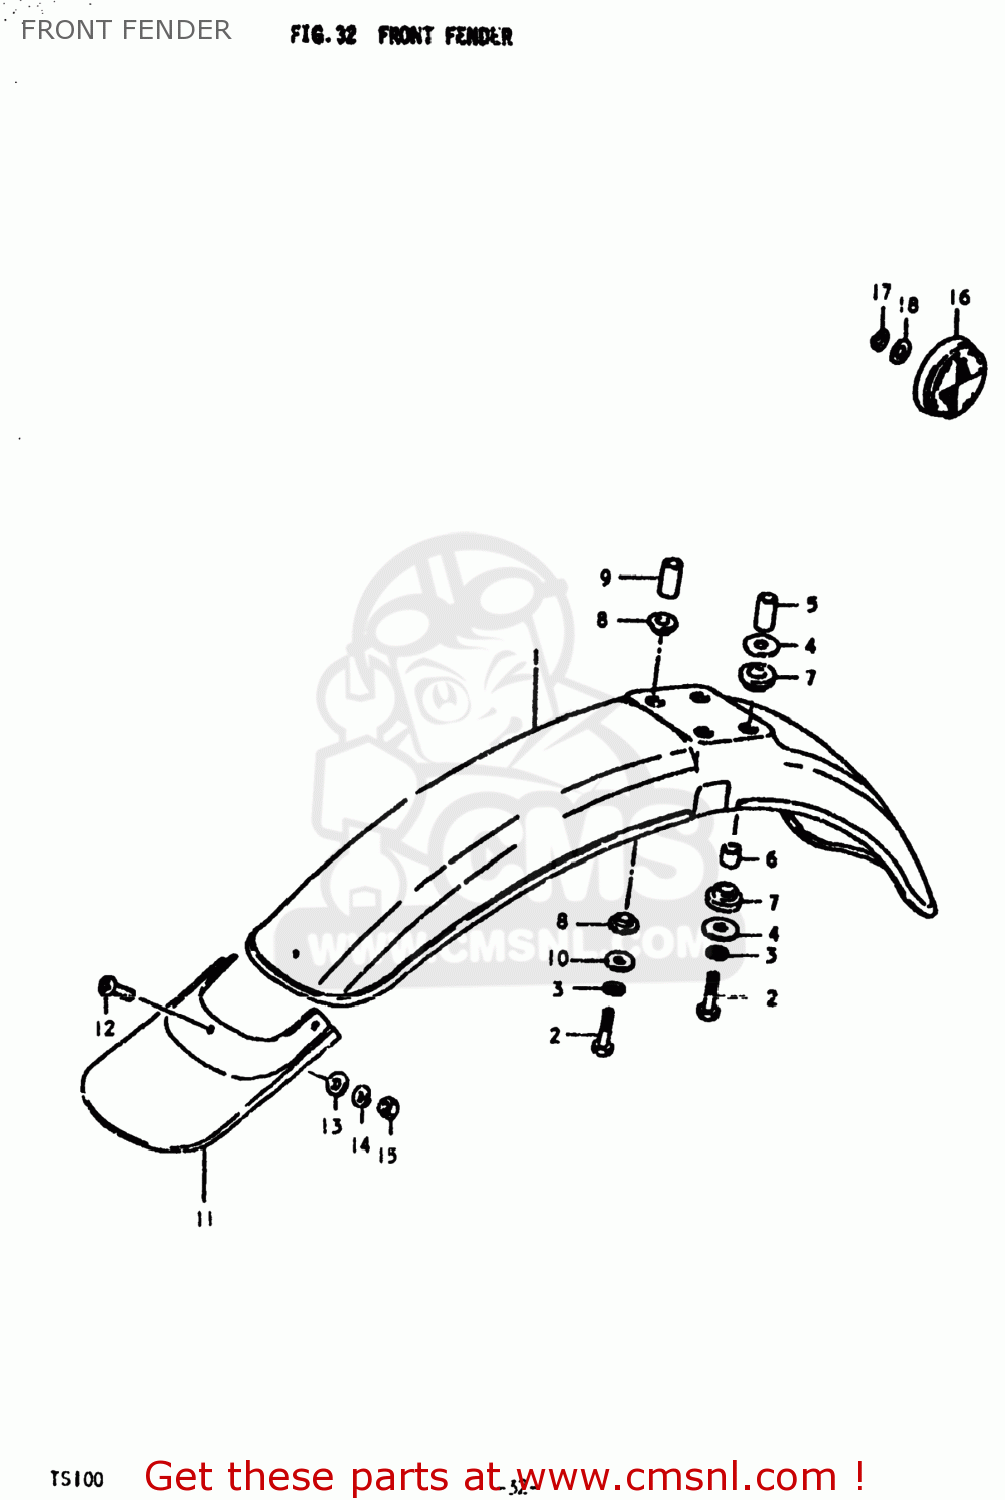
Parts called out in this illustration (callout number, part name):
1	FENDER,FRONT
2	BOLT
3	LOCK WASHER
4	WASHER (6.5X24X1.2)
5	SPACER
6	SPACER (6.5X10.5X13.5)
7	CUSHION
8	SPACER
9	SPACER (6.8X10X20)
10	WASHER
11	MUD FLAP,FRONT FENDER
12	SCREW
13	WASHER
14	LOCK WASHER
15	NUT
16	REFLEX REFLECTOR,FR
17	LOCK WASHER
